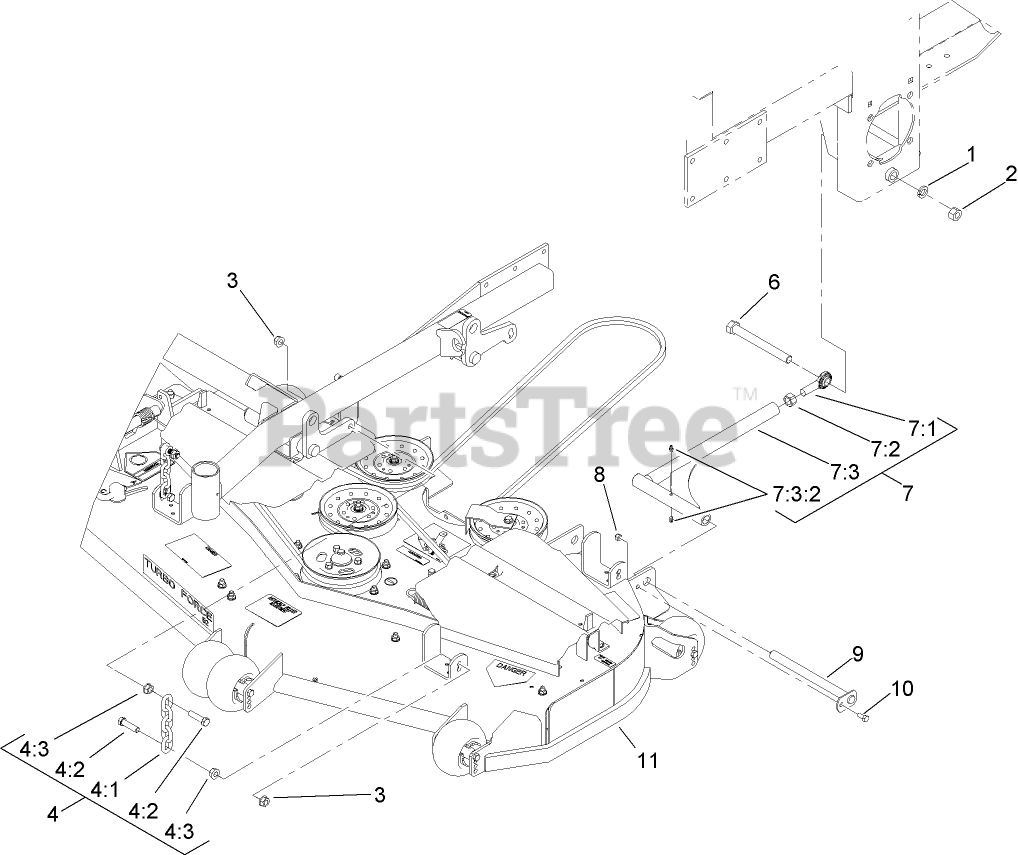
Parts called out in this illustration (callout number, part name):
1	WASHER-LOCK
2	NUT-HEX
3	NUT-HF
4	DECK CHAIN ASM
4:1	CHAIN-LIFT, DECK
4:2	SCREW-HH
4:3	NUT-HF
6	SCREW-HH
7	STRUT ASM
7:1	BALLJOINT-SPHERICAL
7:2	NUT-HEX
7:3	STRUT-DECK
7:3:2	FITTING-GREASE
8	NUT-LOCK, NI
9	PIN-STRUT
10	SCREW-HH
11	DECK ASM
